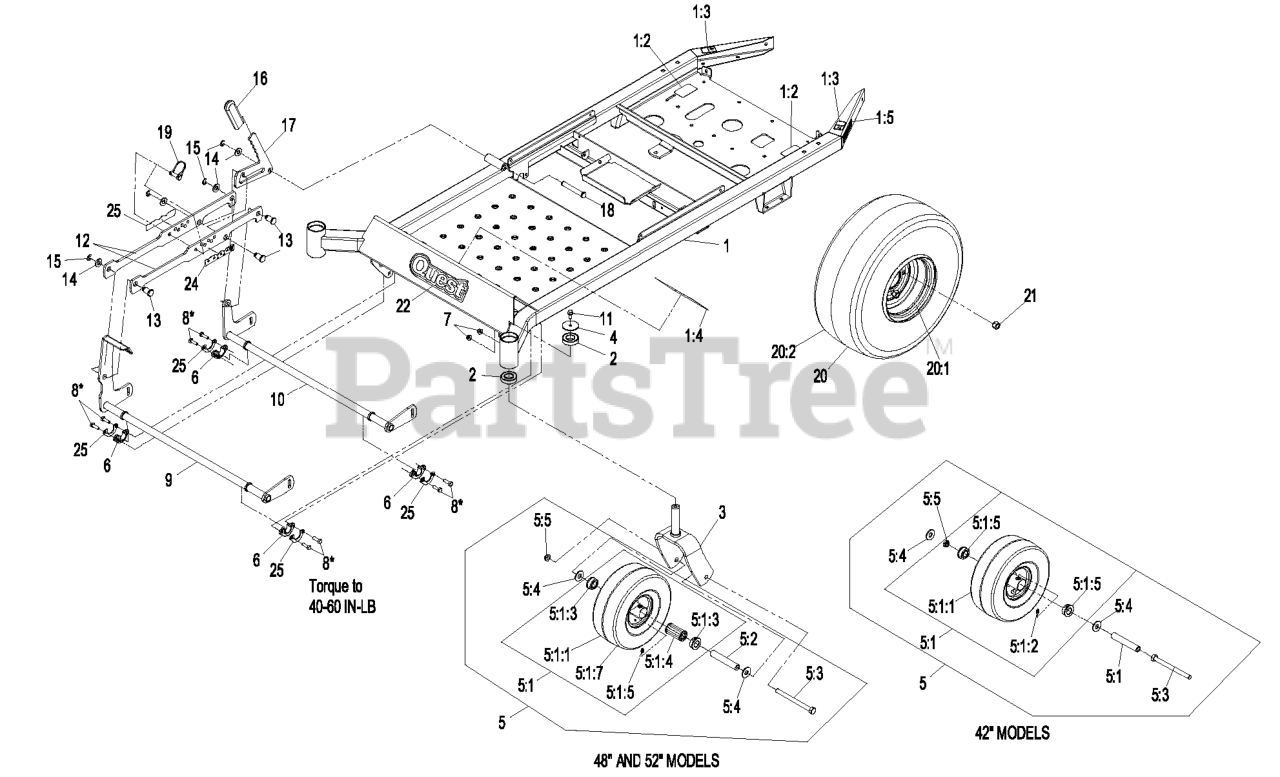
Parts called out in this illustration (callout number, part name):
1:2	DECAL-DRIVE RELEASE
1:3	DECAL-WARNING
1:4	DECAL-SAFETY
1:5	DECAL-ARRESTER, SPARK
2	BEARING-BALL
3	WLD,CASTER FORK
5	ASM,SAWTOOTH WHEEL
5:1	FRONT WHEEL AND TIRE ASM
5:1:2	BUSHING-FLANGE
5:1:3	BEARING
5:1:4	FITTING-GREASE
5:1:5	TUBE-INNER (W/VALVE)
5:2	BUSHING-SPANNER
5:3	SCREW-HH
5:4	WASHER-FLAT
5:5	NUT-HEX
6	KIT-BEARING AND GUSSET
7	NUT-HF, NI
8	SCREW-HH
9	WLD,FRONT SHAFT
10	WLD,REAR SHAFT
11	SCREW-HHF
14	WASHER-FLAT
15	RING-RETAINING, EXTERNAL
16	GRIP-LEVER
18	PIN-CLEVIS
19	PIN-LYNCH
20	WHEEL AND TIRE ASM
21	NUT-LUG
22	DECAL,QUEST LOGO
23	DECAL,HEIGHT OF CUT
24	DECAL,HEIGHT OF CUT
25	GUSSET - DECK LIFT
